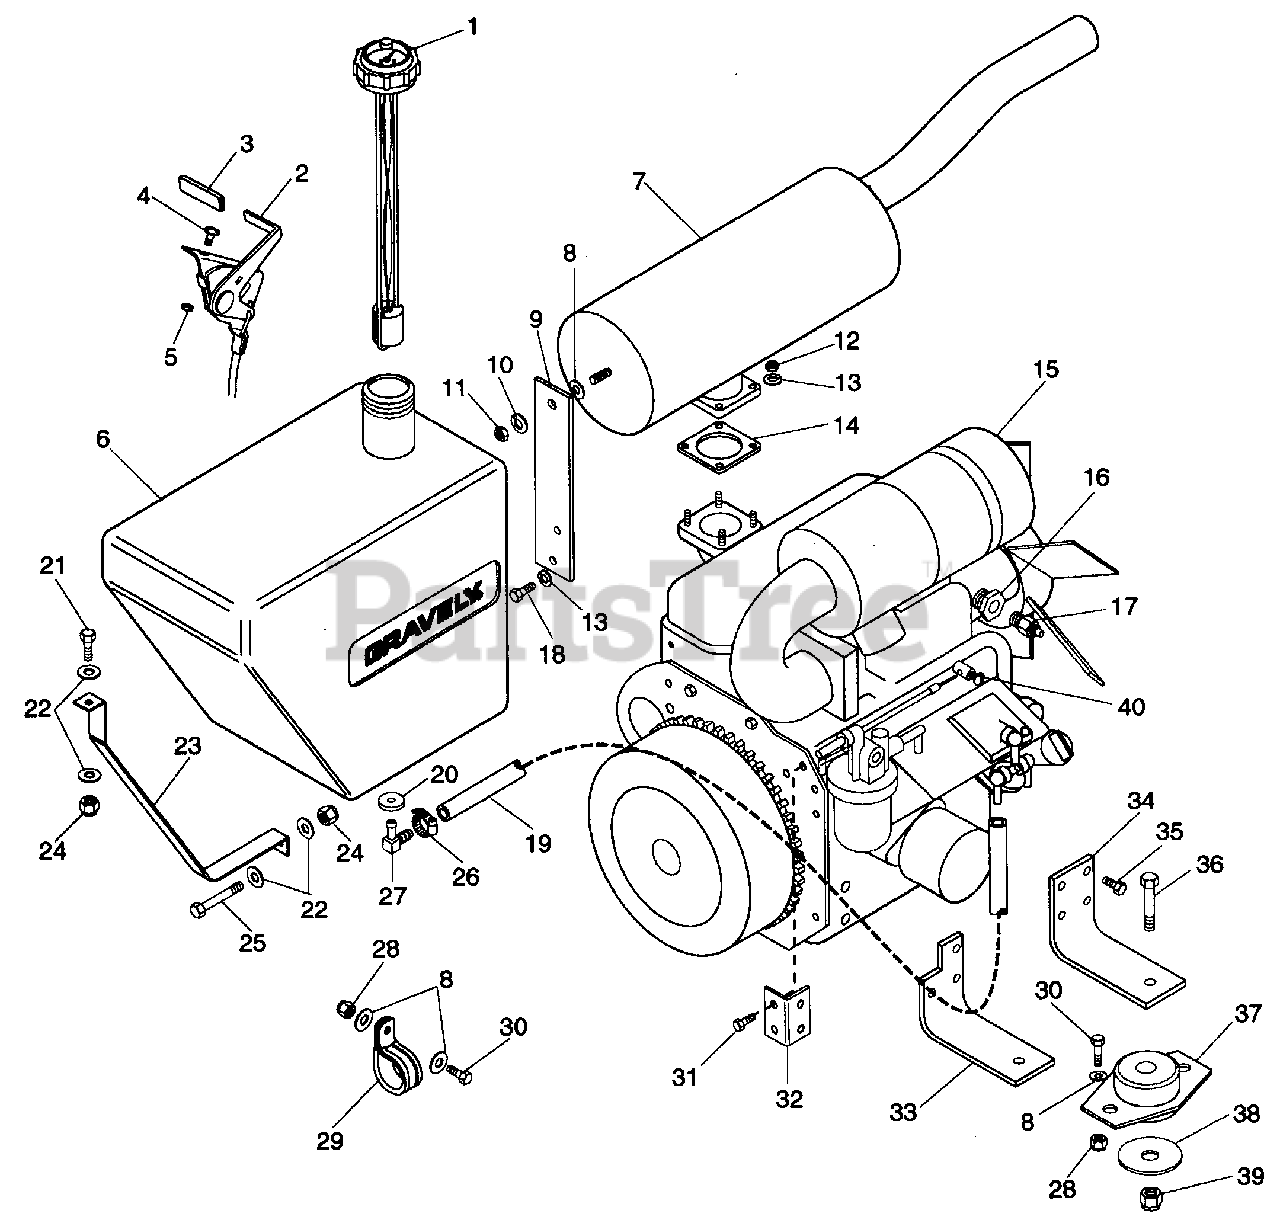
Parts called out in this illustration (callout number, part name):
1	GAUGE, FUEL
2	THROTTLE CABLE ASS'Y
3	GRIP
4	SCR-MACH 10-32 X .50 PH D
5	NUT-LK 10-32 NY PL
6	TANK, FUEL
7	MUFFLER, YANMAR
8	WSHR-FL-STL .406 X .812 X .065 PL
9	BRACE, MUFFLER
10	WSHR-LOCK .375 X .094 MED PL
11	NUT-HEX .375-16
12	NUT-HEX M8 X 1.25 PL
13	WSHR-LOCK .313 X .078 PL
14	GSKT, EXHAUST
15	ENGINE, YANMAR
16	ADPT, TEMPERATURE SENDER
17	SENDER, TEMPERATURE
18	BLT-HEX M8 X 1.25 X 16MM PL
19	GAS LINE-BULK
20	BUSHING
21	BLT-HEX .31-18 X 2.00 PL GR 5
22	WSHR-FL-STL .344 X .688 X .065
23	STRAP, GAS TANK
24	NUT-LK-NYL .312-18 PL
25	BLT-HEX .31-18 X .75 PL GR 5
26	HOSE CLAMP
27	FTG-TANK 1.37 X .406 PL
28	NUT-LK-NYL .375-16 PL
29	CLAMP, STEEL 1.0
30	BLT, HEX .38-16 X 1.00 PL GR 5
31	BLT-HEX M8-1.25 X 16MM PL
32	BRACKET, CONTROL
33	MOUNT, ENGINE
34	MOUNT, ENGINE
35	BLT-HEX M12-1.75 X 25MM PL
36	BLT-HEX .50-13 X 2.75 PL GR 5
37	MOUNT, ENGINE
38	WSHR-SNUB-STL .53 X 2.38 X .125
39	NUT-LK-NYL .50-13 PL
40	SWIVEL ASSY
